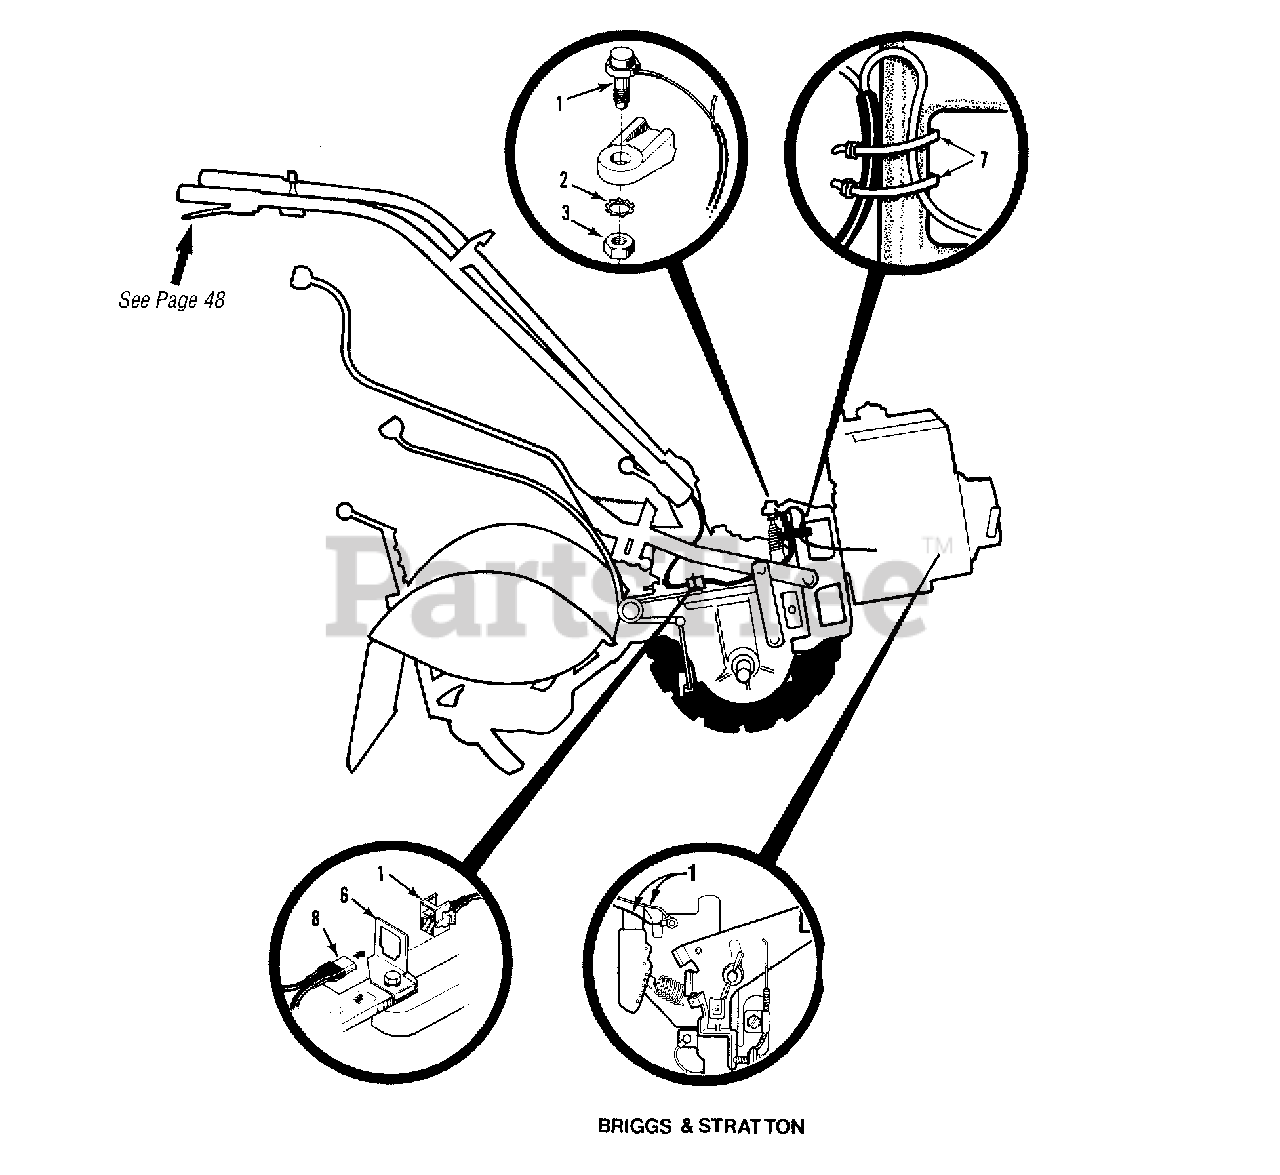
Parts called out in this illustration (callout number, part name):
1	Engine Wire Harness Assy-forward interlock system
2	Lockwasher-external tooth, 7/16"
3	Nut-hex, 7/16"-20
6	Clip-for plug connector
7	Tie-plastic
8	Handlebar Wire Harness Assy
